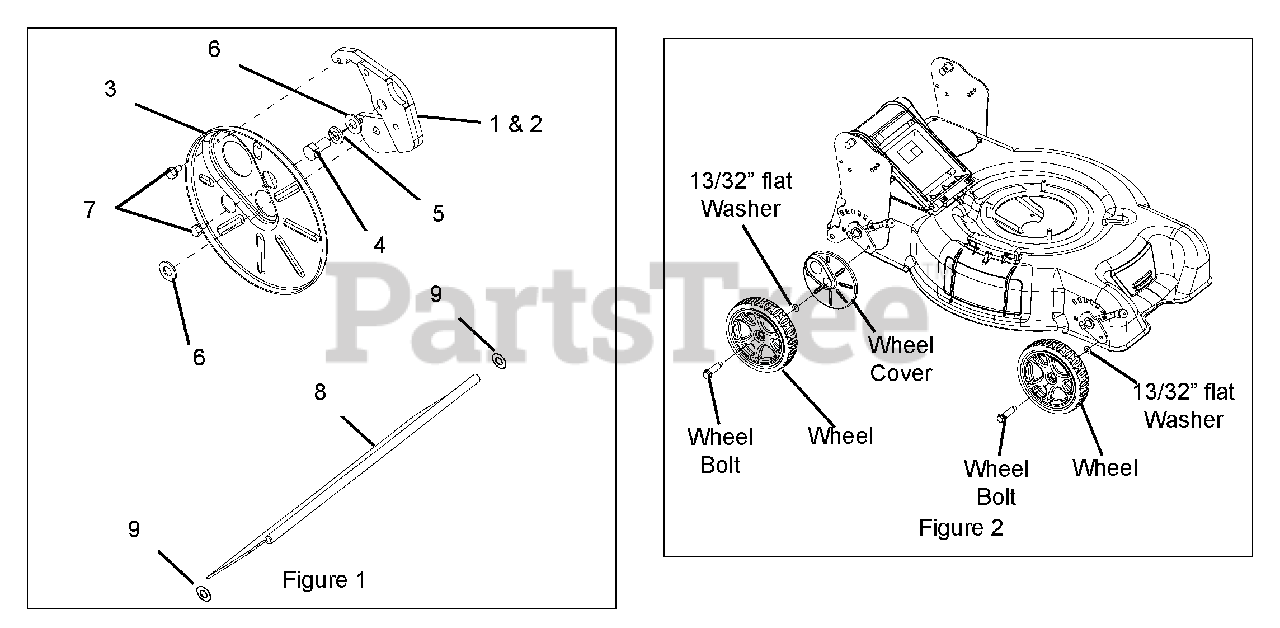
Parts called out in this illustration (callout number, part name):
1	External Left Hand Bracket
2	External Right Hand Bracket
3	Wheel Cover
4	3/8" x 3/4" Hex Bolt
5	3/8" Lock Washer
6	13/32" Flat Washer
7	3/8" Tapping Screw
9	3/8" Push-On Retainer
